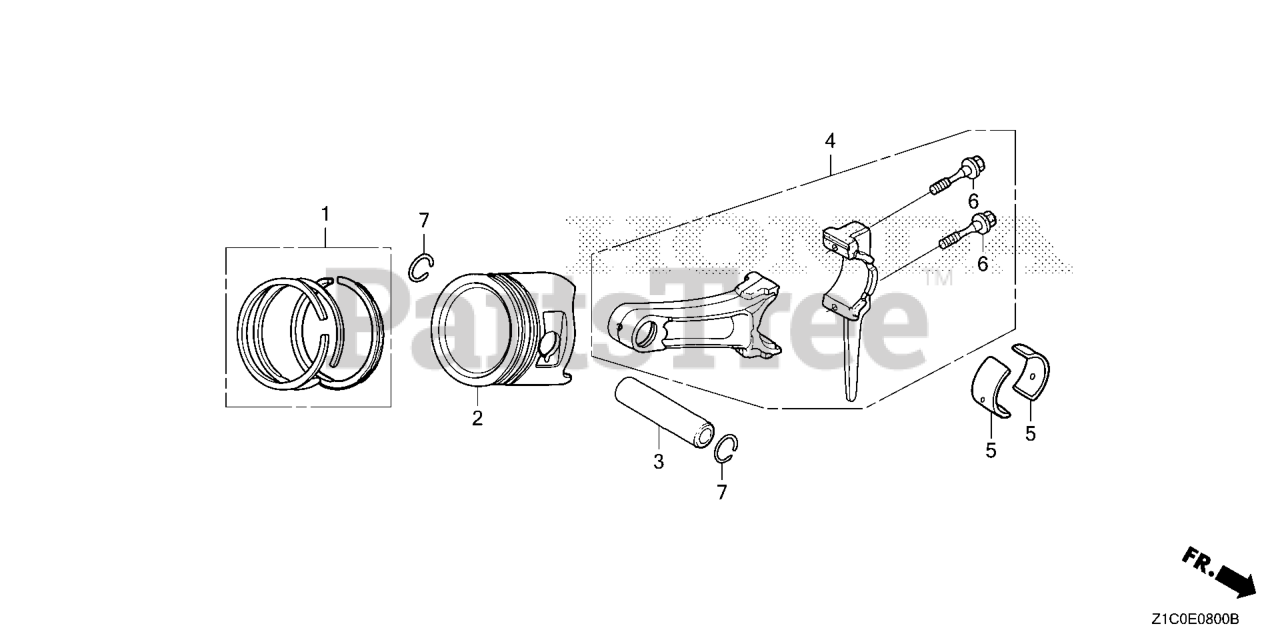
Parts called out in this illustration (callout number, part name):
1	RING SET, PISTON (STD) (TEIKOKU)
2	PISTON (STD)
3	PIN, PISTON
4	ROD ASSY., CONNECTING (STD)
6	BOLT, CONNECTING ROD
7	CLIP, PISTON PIN (20MM)
